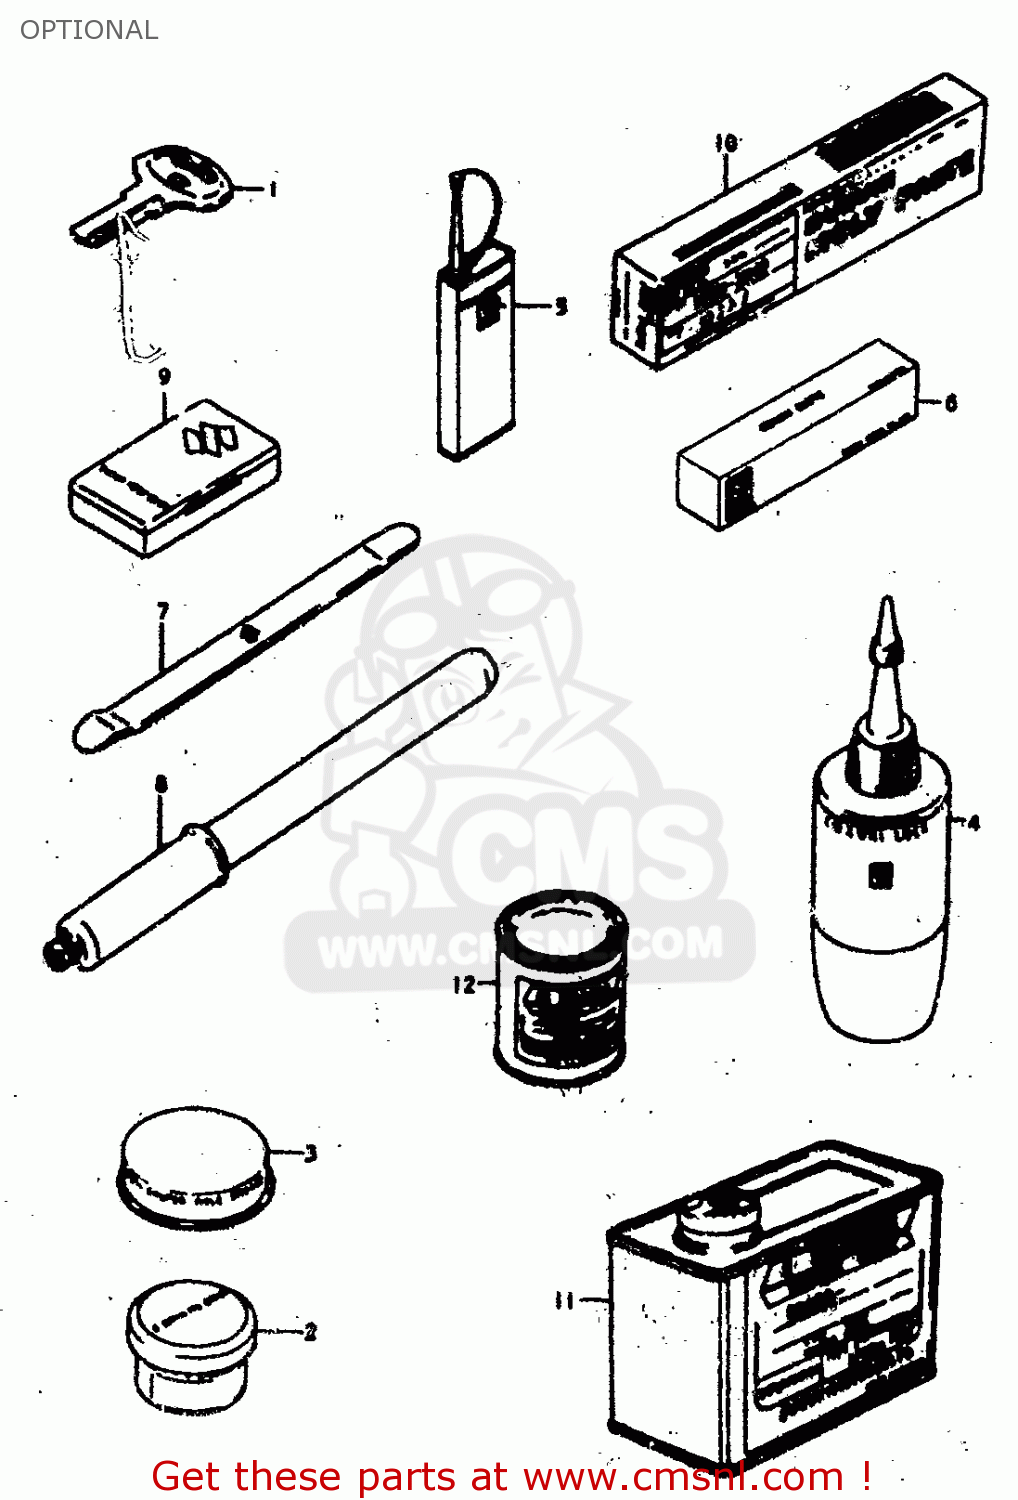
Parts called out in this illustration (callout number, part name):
1	KEY,BLANK
2	GREASE,PBC FOR BRK PAD 20G
3	GREASE,SILICON 20G
4	THREAD LOCK NO.1303B PURPL 50G
5	THREAD LOCK NO.1401 CLEAR 200G
6	BOND 1104
7	LEVER,TIRE
8	INFLATOR, AIR
9	TUBE REPARING TOOL
10	SUZUKI MOLY PASTE
11	PAINT (BLACK)
12	PAINT,BLACK
